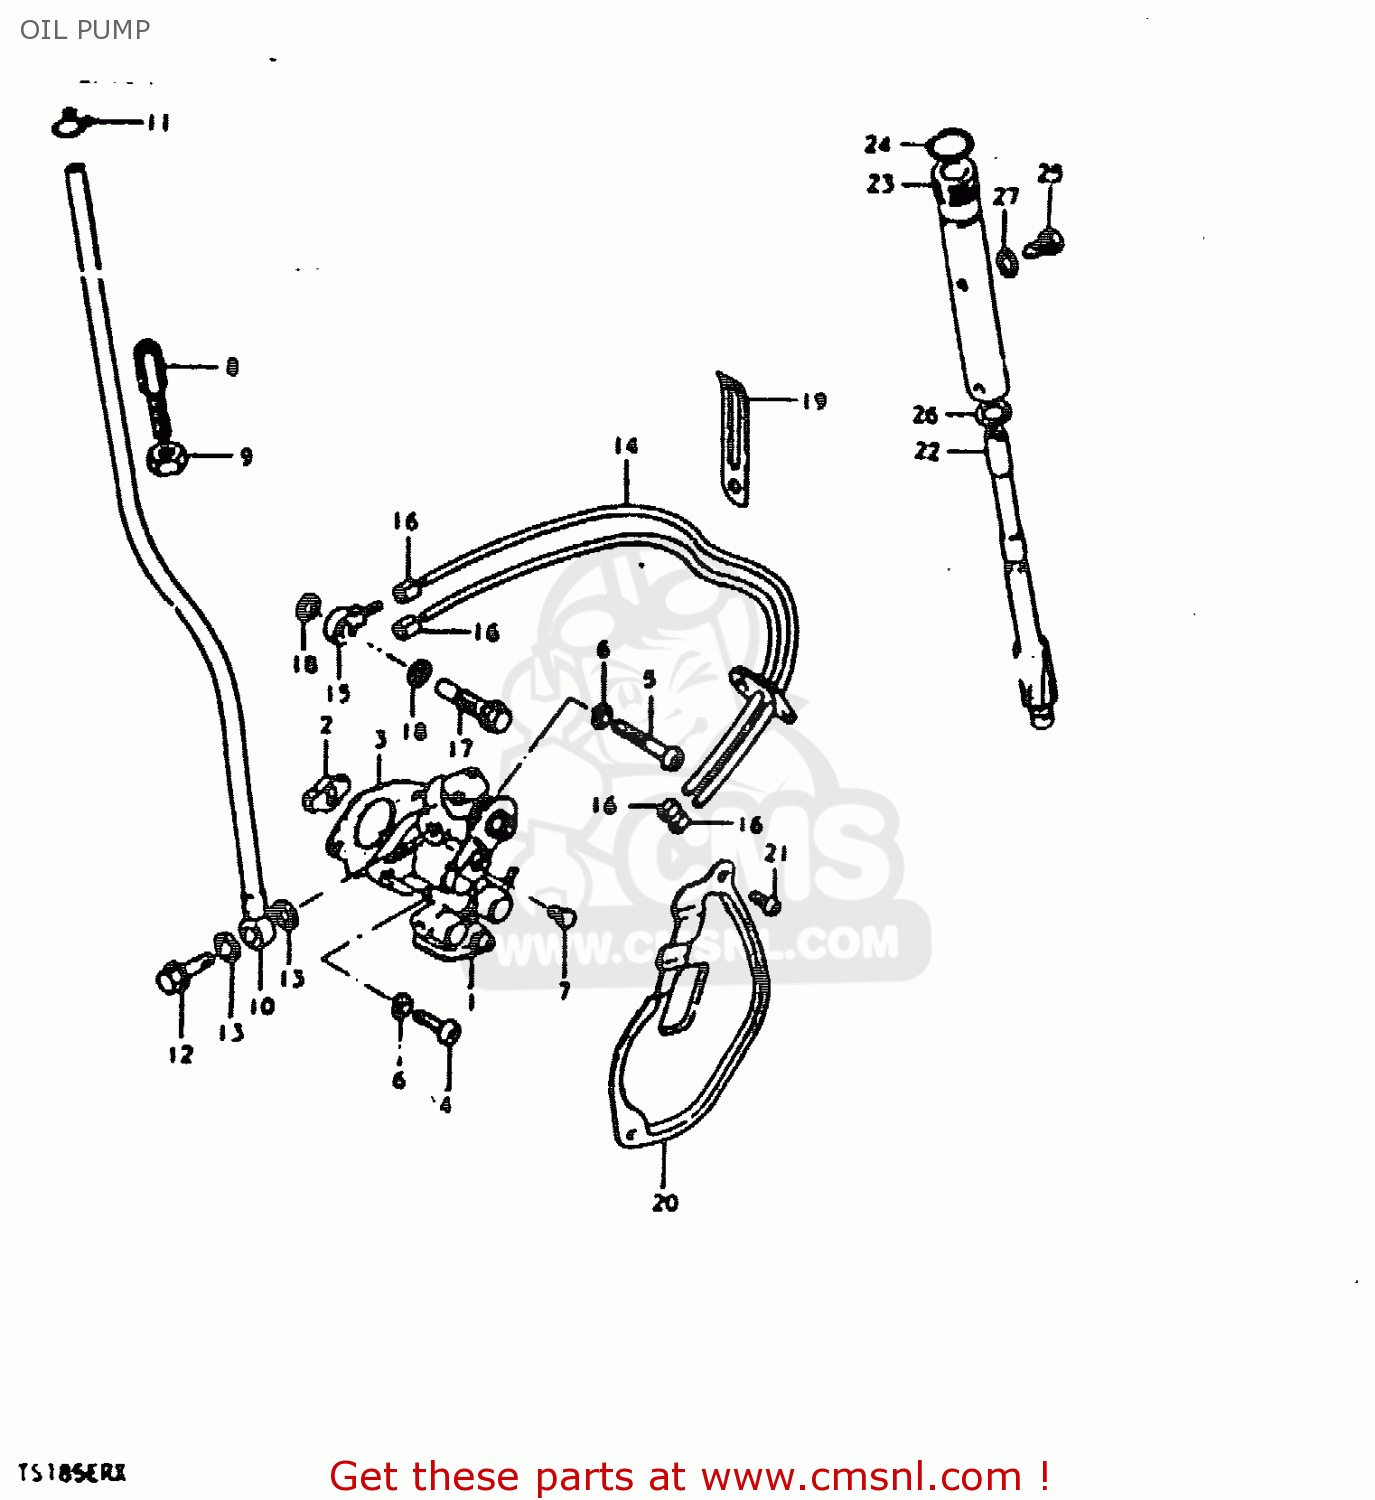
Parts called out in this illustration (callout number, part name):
1	PUMP ASSEMBLY,OIL
2	PIECE,OIL PUMP DRIVE
3	GASKET,OIL PUMP (NAS)
4	SCREW
5	SCREW
6	LOCK WASHER
7	TERMINAL,CABLE
8	BOLT
9	NUT
10	HOSE,OIL NO.1
11	CLIP
12	UNION BOLT
13	GASKET(6.2X11X1).2 (NAS)
14	HOSE,OIL NO.2
15	UNION
16	CLIP
17	UNION
18	GASKET(6.2X11X1).2 (NAS)
19	CLAMP L:35
20	CAP,OIL PUMP INSPECTION
21	SCREW
22	GEAR,TACHOMETER DRIVEN
23	SLEEVE,TACHOMETER DRIVE
24	O RING(D:1.3,ID:9.6)
25	BOLT(6X12)
26	WASHER(8X13.7X1)
27	WASHER
